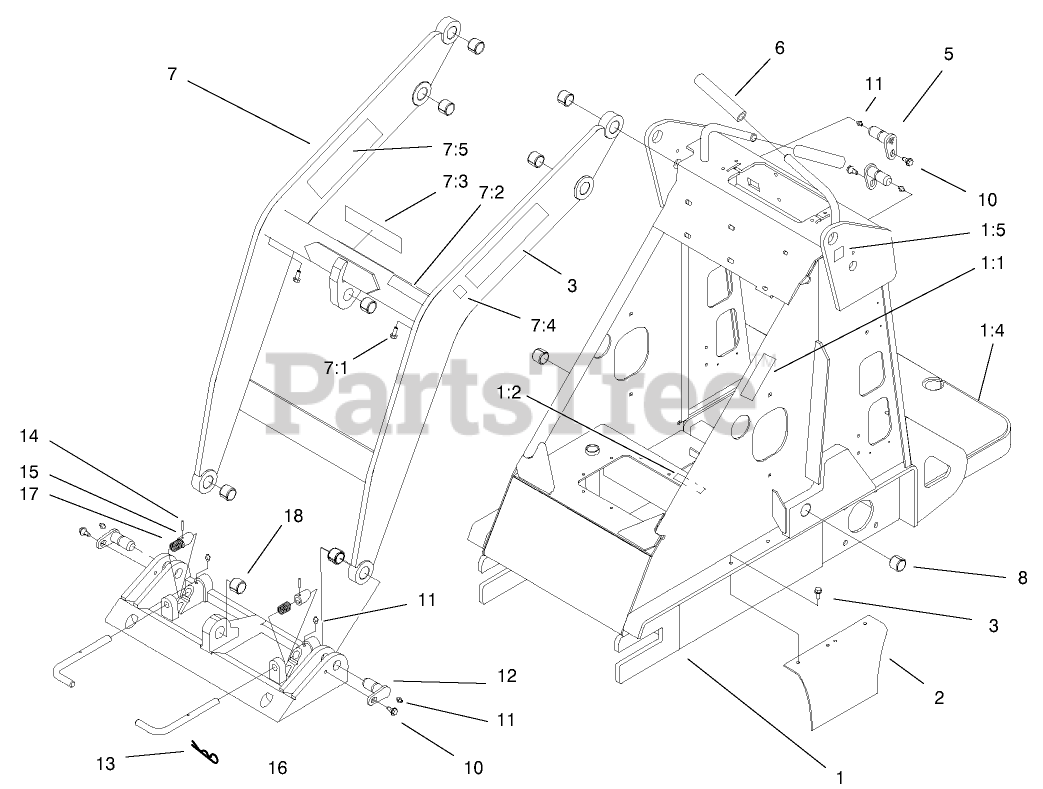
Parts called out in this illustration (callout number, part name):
1	FRAME ASM
1:1	DECAL-WARNING
1:2	DECAL-WARNING
1:4	TREAD-FOOT
1:5	DECAL-POINT, LIFT
2	Cover-Chain
3	SCREW-HWHTF
5	PIN-PIVOT
6	GRIP-CUSHION
7	LOADER ASM
7:1	SCREW-HWHTF
7:2	DECAL-NO RIDERS
7:3	DECAL-CAUTION
7:4	DECAL-POINT, LIFT
7:5	DECAL-DANGER
8	BUSHING-TENSION
10	BOLT-SHOULDER
11	FITTING-GREASE
12	PIN-PIVOT
13	PIN-COTTER
14	PIN-SPECIAL
15	CAM-ATTACH, QUICK
17	SPRING-COMPRESSION
18	BUSHING-TENSION
